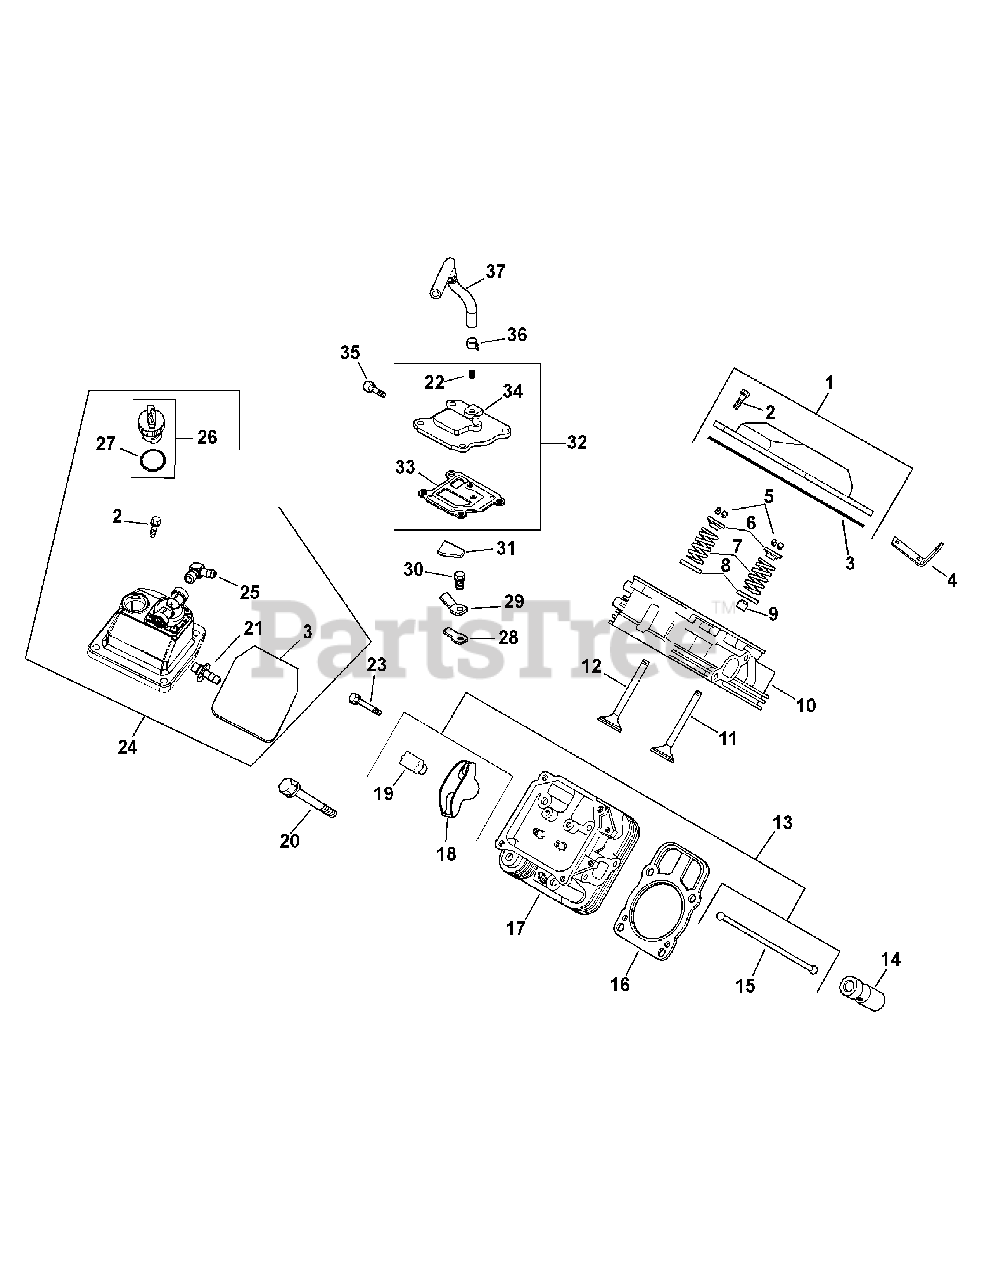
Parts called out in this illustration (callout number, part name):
1	Kit, oil fill rocker cover
2	Screw, hex flange M6x1.0x30
3	O-Ring, valve cover
4	Strap, lifting
5	Kit, retainer
6	Cap, valve spring
7	Spring, valve
8	Retainer, spring
9	Seal, valve stem
10	Head assembly, #1 cylinder
11	Valve, intake (Std.)
11	Valve, intake (.25)
12	Valve, exhaust (Std.)
12	Valve, exhaust (.25)
13	Kit, valve train
14	Lifter, valve
16	Kit, cyl head gskt
17	Head assembly, #2 cylinder
19	Pivot, rocker arm
20	Screw, Flg, M10x1.5x90
21	Fitting, 45°
22	Plug, ctsk pipe 1/8"
23	Screw, hex flange M6x1.0x34
24	Kit, fuel pump
25	Fitting, 90°
26	Cap assembly, oil fill
27	O-Ring, dipstick
28	Reed, breather
29	Retainer, reed
30	Screw, hex. flange M5x0.8x10
31	Filter, breather
32	Kit, breathe
33	Gasket, breather
34	Cover, breather
35	Screw, hex ange M6x1.0x20
36	Clamp, hose
37	Hose, breather
